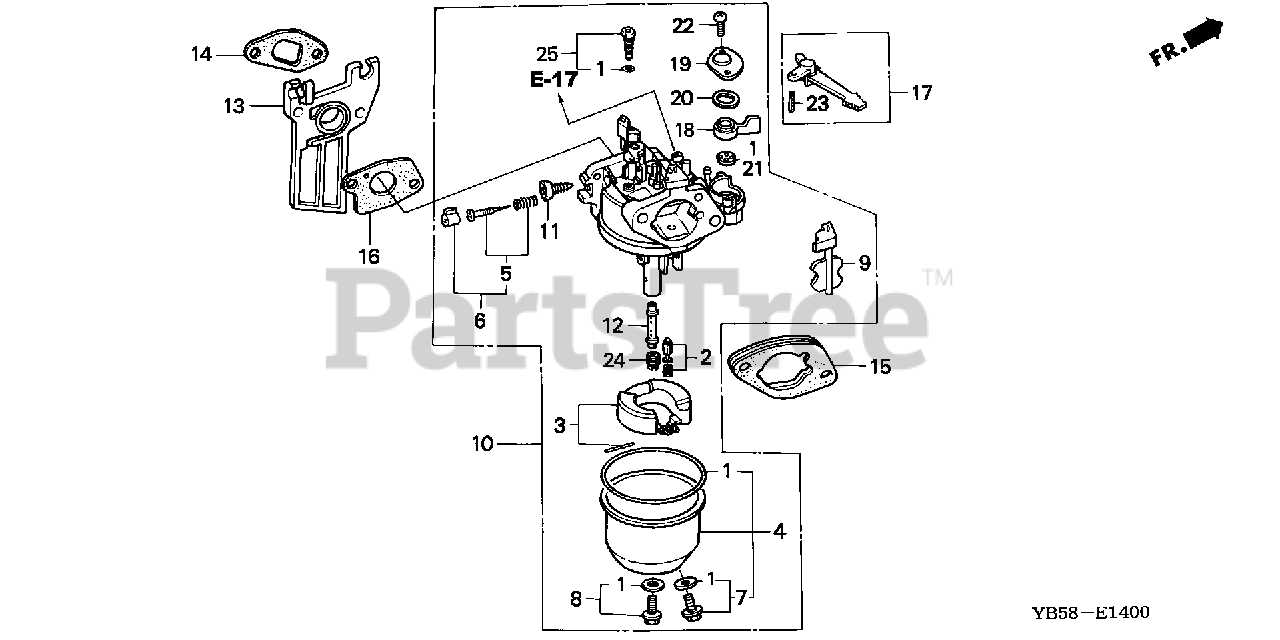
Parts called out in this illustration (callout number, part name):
1	GASKET SET
2	VALVE SET, FLOAT (SEAT NOT INCLUDED)
4	CHAMBER SET, FLOAT (CARBURETOR NO.)
5	SCREW SET, PILOT (CARBURETOR NO.)
7	SCREW SET, DRAIN
8	SCREW SET
9	CHOKE SET (CARBURETOR NO.)
10	CARBURETOR ASSY. (BE06H C)
11	SCREW, THROTTLE STOP
12	NOZZLE, MAIN (CARBURETOR NO.)
13	INSULATOR, CARBURETOR
14	GASKET, INSULATOR
15	SPACER, CARBURETOR
16	GASKET, CARBURETOR
17	LEVER, CHOKE (STD)
18	LEVER, PETCOCK
19	PLATE, LEVER SETTING
20	SPRING, PETCOCK LEVER
21	GASKET, PETCOCK
22	SCREW, PAN (3X6)
22	SCREW, PAN (3X8)
23	PIN, SPRING (2X12)
24	JET, MAIN (#68)
24	JET, MAIN (#70) (CARBURETOR NO.)
24	JET, MAIN (#70)
24	JET, MAIN (#72) (CARBURETOR NO.)
24	JET, MAIN (#72)
25	JET SET, PILOT (#35) (CARBURETOR NO.)
25	JET SET, PILOT (#38) (CARBURETOR NO.)
